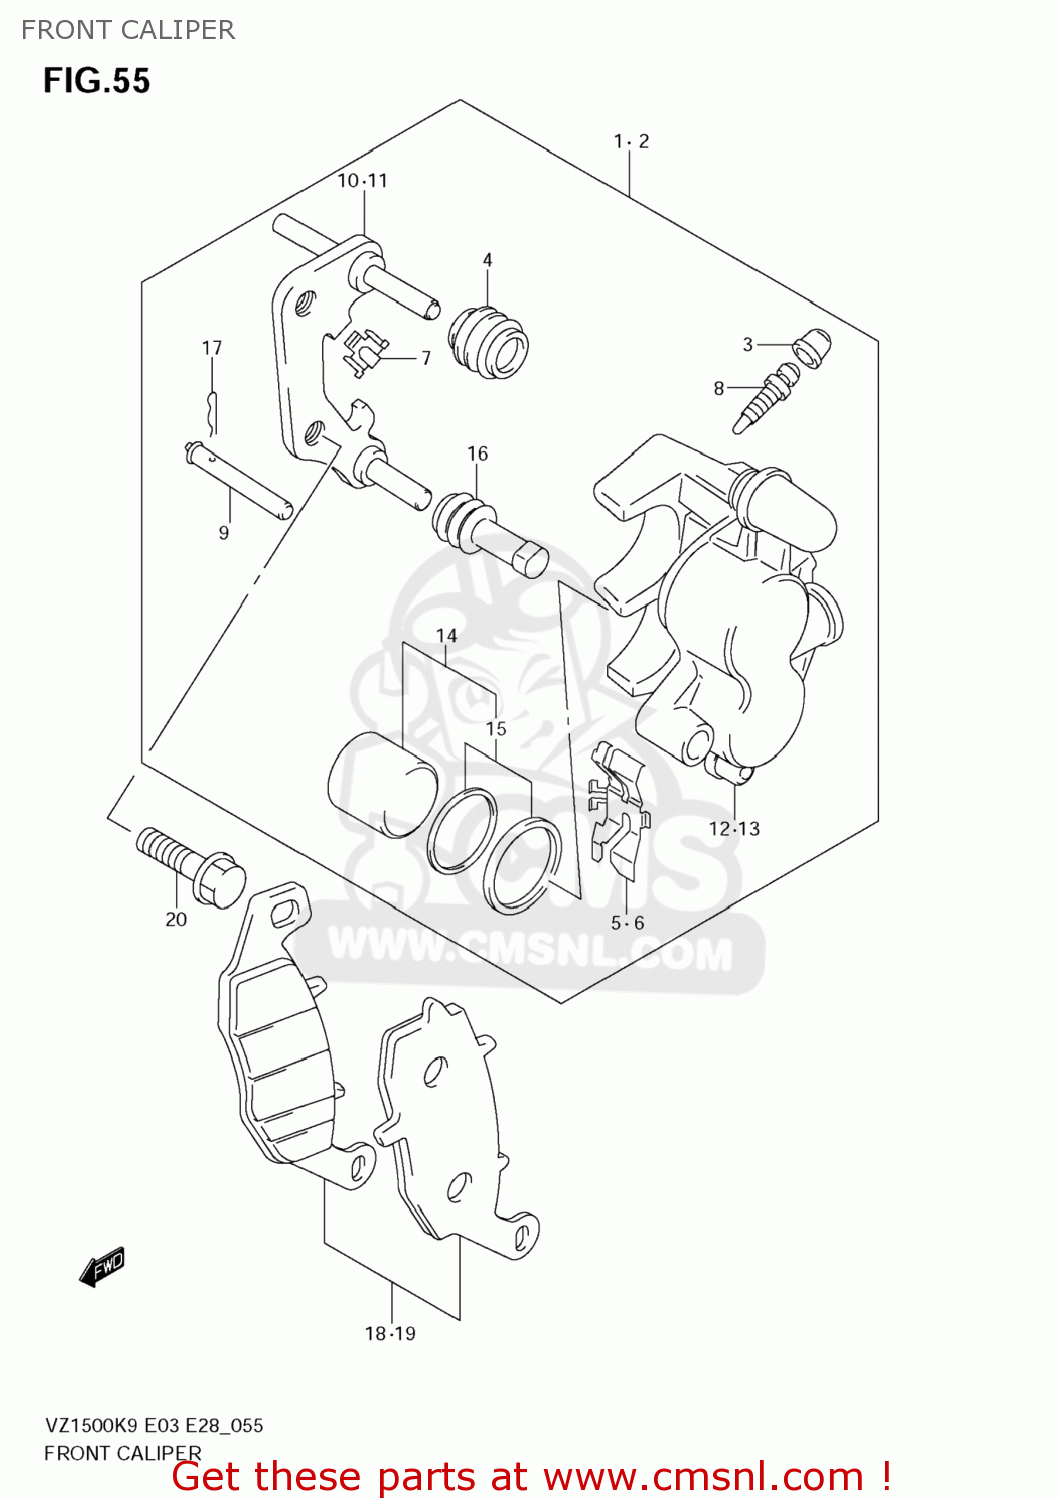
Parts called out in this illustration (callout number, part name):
1	CALIPER ASSY,FR,R
2	CALIPER ASSY,FR,L
3	CAP,BLEEDER PLUG
4	BOOT,AXLE
5	SPRING,PAD,R
6	SPRING,PAD,L
7	GUIDE,PAD
8	BLEEDER
9	PIN,PAD
10	CARRIER,CALIPER,R
11	CARRIER,CALIPER,L
12	HOUSING, CALIPER RH
13	HOUSING, CALIPER LH
14	PISTON SET
15	SEAL SET,PISTON
16	INSULATOR,AXLE
17	CLIP,PAD PIN
18	PAD SET (NAS)
19	PAD SET (NAS)
20	BOLT(10X30)
